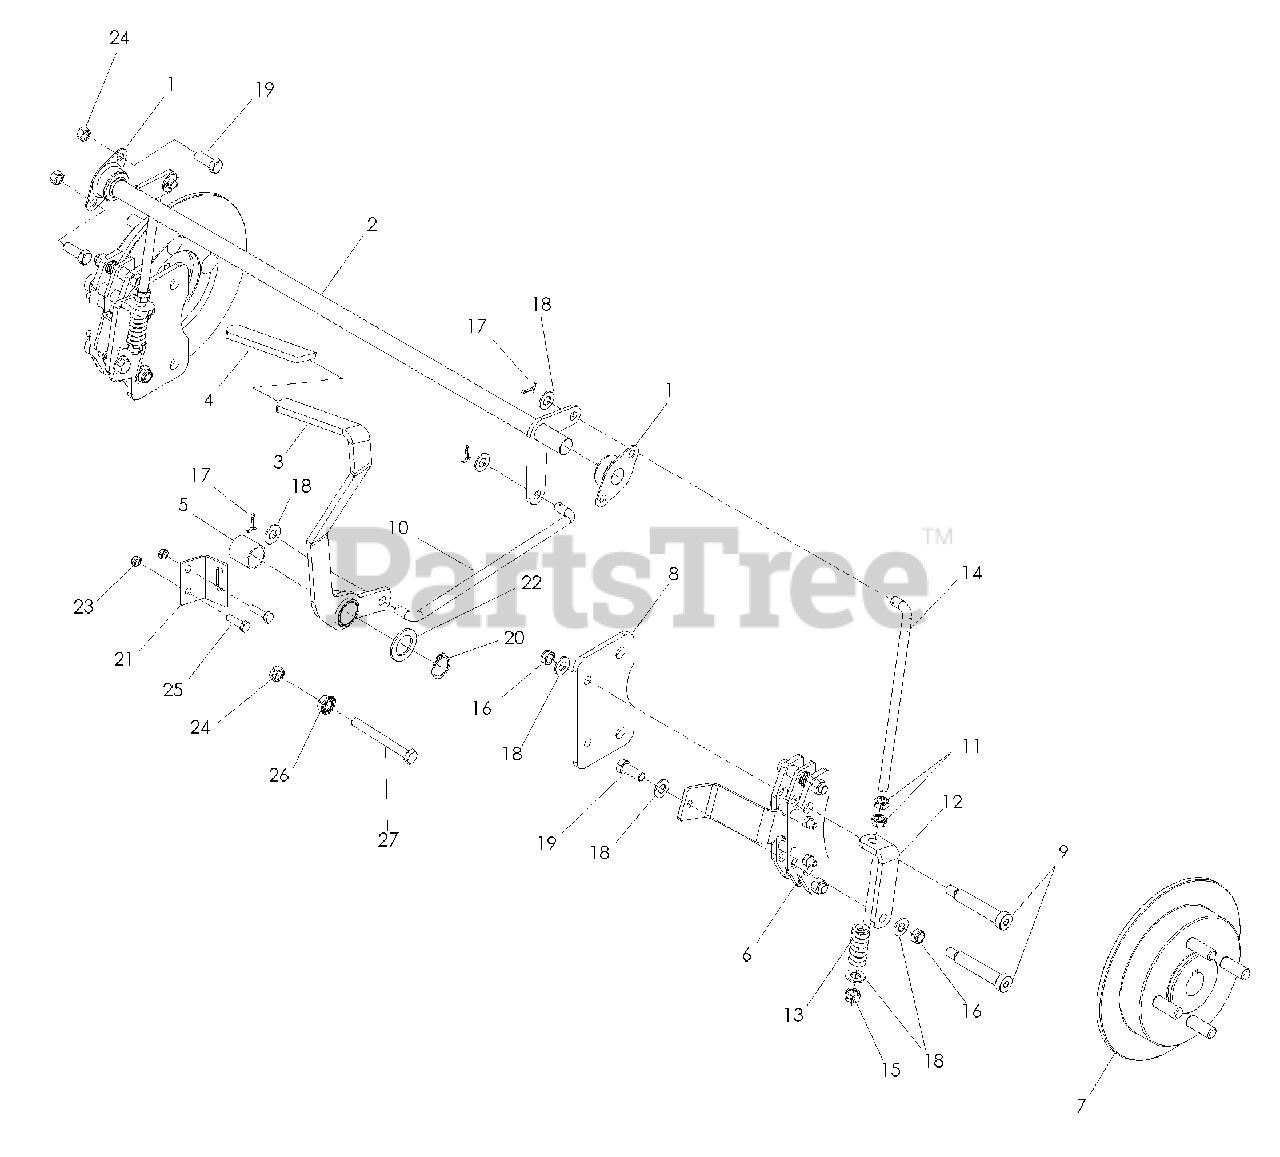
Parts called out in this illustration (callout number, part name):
1	BEARING, FLANGED
2	BRAKE CROSS SHAFT
3	BRAKE LEVER
4	GRIP, PARK BRAKE
8	PLATE, BRAKE
9	SCREW, 3/8-16 x 2 1/2, SKT
10	LINKAGE, BRAKE
11	NUT 3/8-24, JAM
14	LINKAGE, REAR BRAKE
15	NUT 3/8-24 CENTERLOCK
16	NUT 3/8-16 THIN NYLOC
17	PIN COTTER, 3/32 x 3/4
18	WASHER 3/8 SAE FLT
19	HCS 3/8-16 x 1
20	RING, RETAINING EXT 7/8
23	NUT 1/4-20 HEX NYLOC
24	NUT 3/8-16 HEX NYLOC
25	HCS 1/4-20 x 3/4
26	NUT 3/8-16 WHIZLK
27	HCS 3/8-16 x 2 1/2
